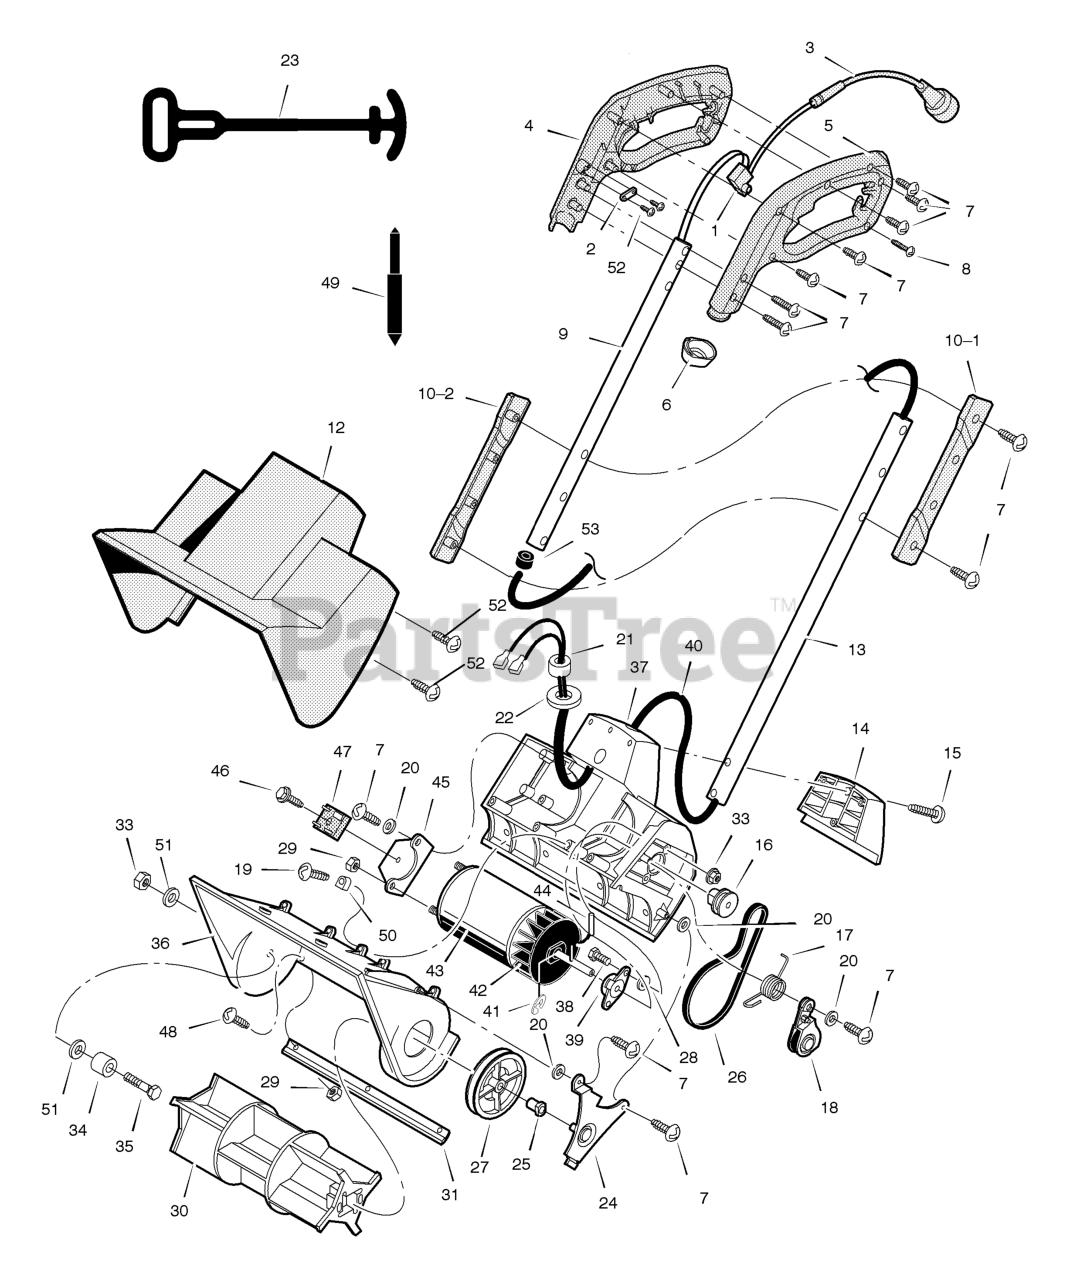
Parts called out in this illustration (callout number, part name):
2	Strain Relief
3	Lead Wire, Connecting
4	Handle, Right Half
5	Handle, Left Half
6	Cover, Grip
7	Screw, #8 X 3/4 Poly
8	Screw, #4 X .5 Hi-Low
9	Tube -Handle, Upper
10	Set, Grip Center 12"
10-1	Order Set
10-2	Order Set
12	Housing, Upper 12"
13	Handle, Lower
14	Housing, Rear 12"
15	Screw, 10-9 X 1.062
16	Pulley, Engine
17	Spring, Torsion
18	Pulley, Idler & Brkt. Assy
19	Screw, #8 X1.00
20	#8 Washer
21	Clamp, Heyco
22	Washer, Flat .505 X 1.00X.06
23	Strain Relief, Cord
24	Bracket, Assy Drive Pulley
25	Bearing-Bronze
27	Pulley, Driven E12"
28	Washer, Plastic
29	Nut, #10-24 CNHKHX
30	Impeller, 12"
31	Blade, Scraper
33	Nut, 1/4-20 WDFL center Lock
34	Spacer, Impeller
35	Screw, 1/4-20X1.00
36	Housing, Impel 12"
37	Housing, Lower 12"
38	Screw, 1/4-20X.50
39	Bearing, Self Align
40	Wire Harness, E12"
41	Ring, Ret E
42	Fan, Motor, Extended
43	Motor, 120V
44	Pin, Grooved
45	Bracket, Motor Mount
46	Screw, #6-32X.75
47	Rectifier, Full Wave
48	Screw, 10-32X.50
49	Probe, Plastic
50	Plug, Retainer
51	Washer, 3/4X1/4X1/16
52	Screw, #8X.375 Poly Grip
53	Protector, Harness
